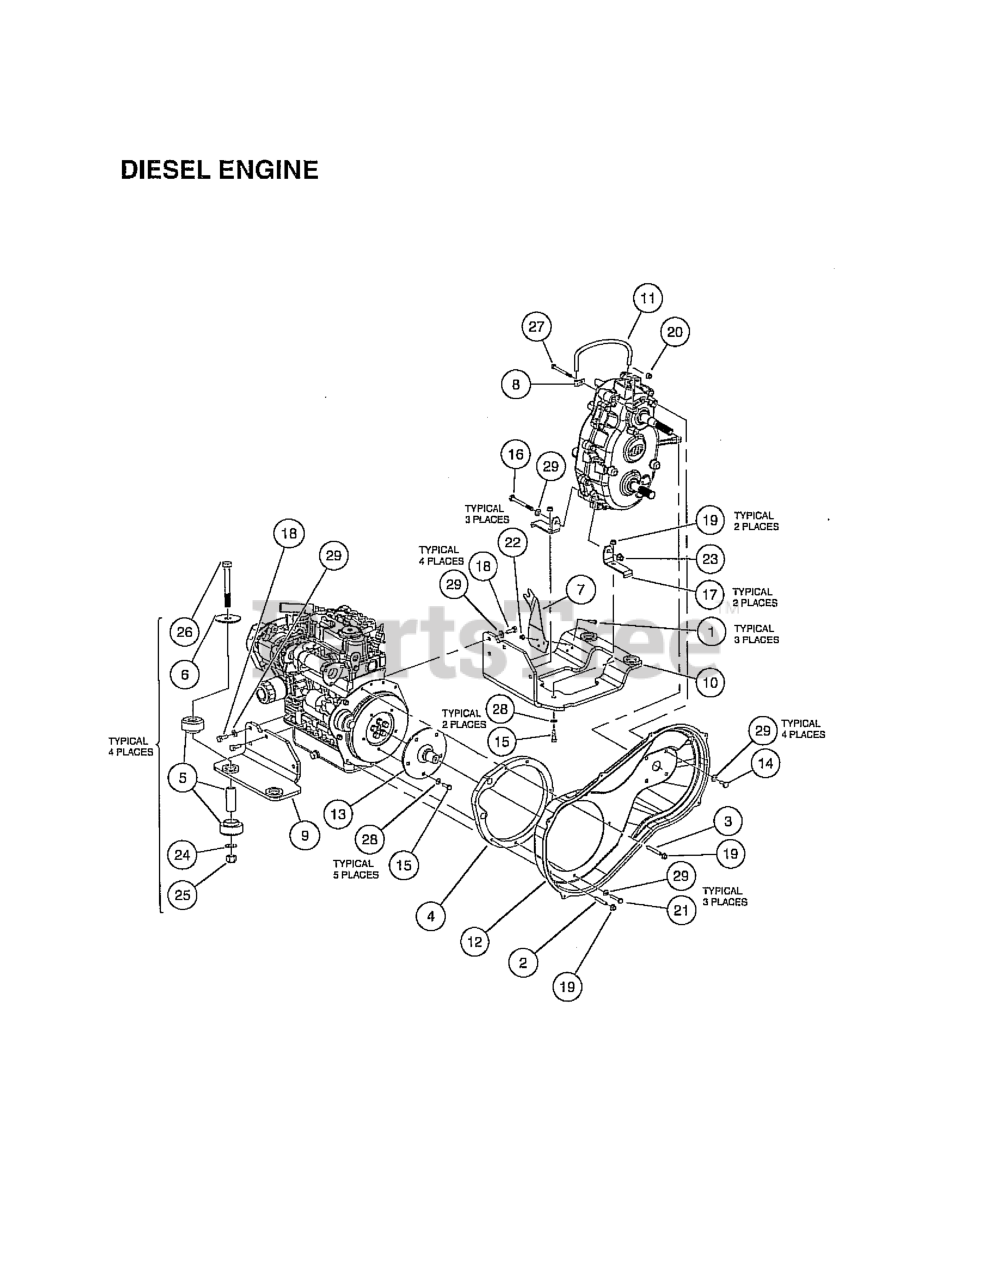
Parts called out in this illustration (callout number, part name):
2	STUD, M8-1.25 X 50MM 2-ENDED
3	STUD, M8-1.25 X 60MM 2-ENDED
4	SPACER, ENGINE, DIESEL
7	BRACKET, FNR TRANS CABLE
8	P-CLAMP, INSULATED .312 IN
9	Plate, Engine Mounting, Weld, Left-Hand
10	PLATE, ENG MTG, WELD, RH
11	HOSE, VENT, TRANSMISSION
12	COVER, CVT INNER, DIESEL
13	SHAFT, CVT ADAPTER
14	BOLT, M10 X 1.5 X 20 LOCTITE
15	BOLT, M8 X 1.25 X 25 LOCTITE
16	BOLT, M10 X 1.5 X 100 LOCTITE
17	BRACKET, TRANSMISSION MTG
18	BOLT, M10 X 1.25 X 25 LOCTITE
19	NUT FLG, M8 X 1.25 MECH DEF
20	LOCK NUT, FLG M8 X 1.25 NYLON
21	BOLT, M8X1.25X40 LOCTITE
22	NUT FLG, M6 X 1.0 NYLON
23	NUT FLG M10 X 1.5 NYLON
24	WASHER, M12 HARD
25	LOCKNUT, M12X1.75 NYLON INSERT
26	BOLT, M12 X 1.75 X 90
27	BOLT, M8 X 1.25 X 80
28	WASHER, M8 HARD
29	WASHER, M10 HARD
